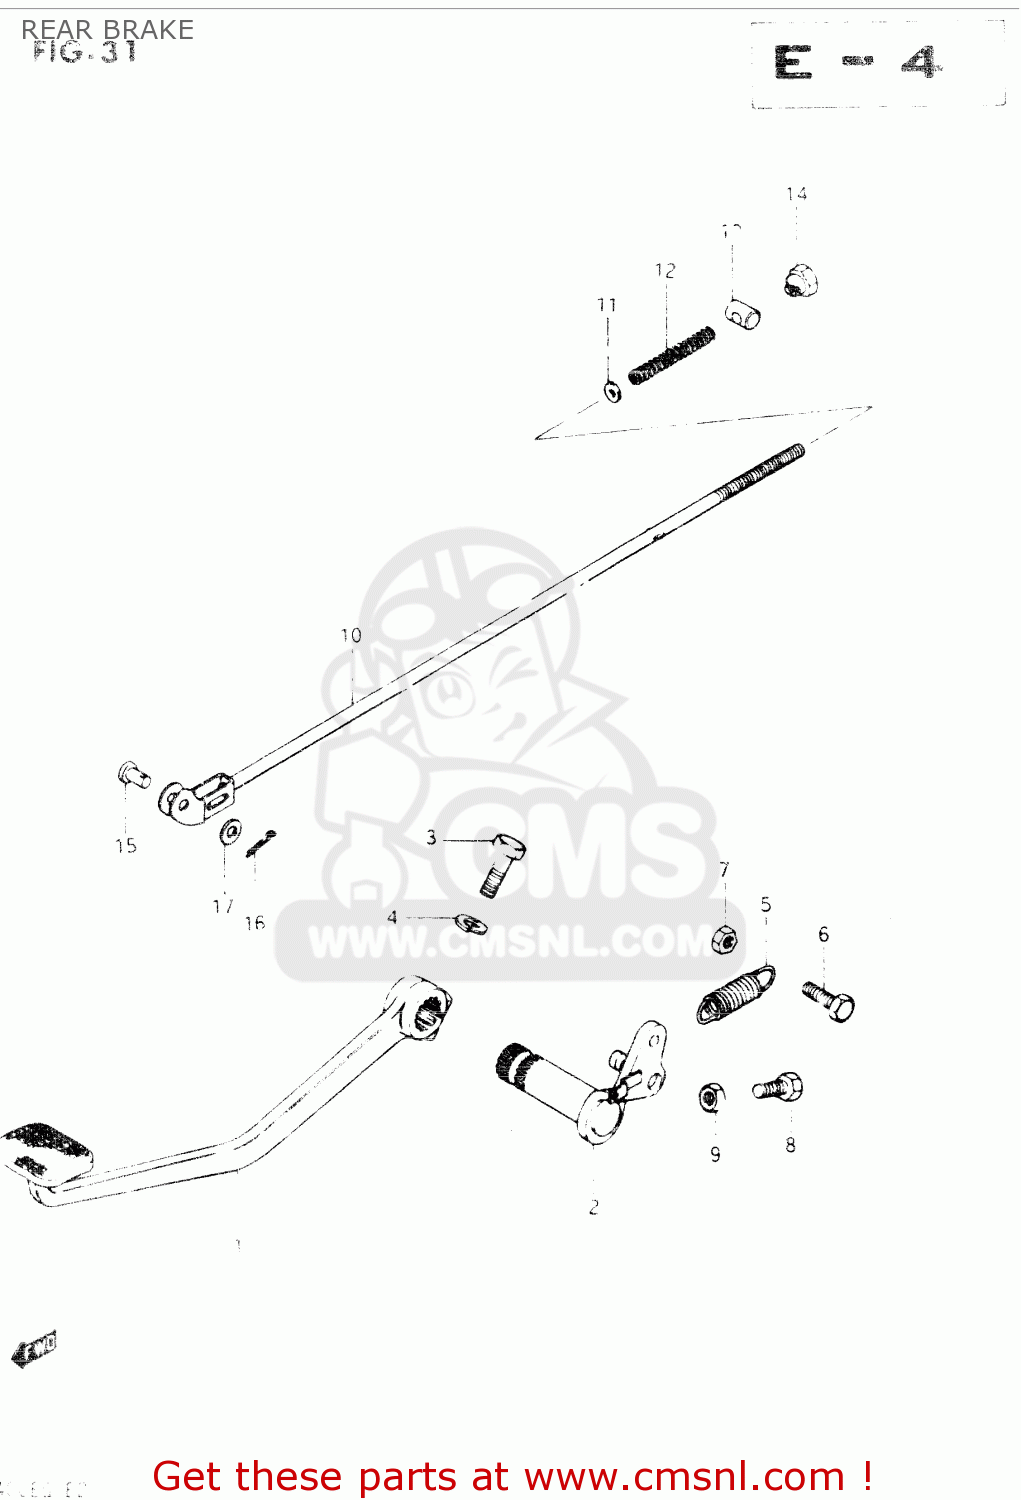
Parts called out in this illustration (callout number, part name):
1	PEDAL,BRAKE
2	ARM,BRAKE PEDAL
3	BOLT
4	LOCK WASHER
5	SPRING
6	BOLT
7	NUT
8	BOLT
9	NUT
10	ROD ASSY,RR BRAKE
11	WASHER
12	SPRING
13	PIN
14	NUT (6MM)
15	PIN(L:13.5)
16	PIN 20X20
17	WASHER
